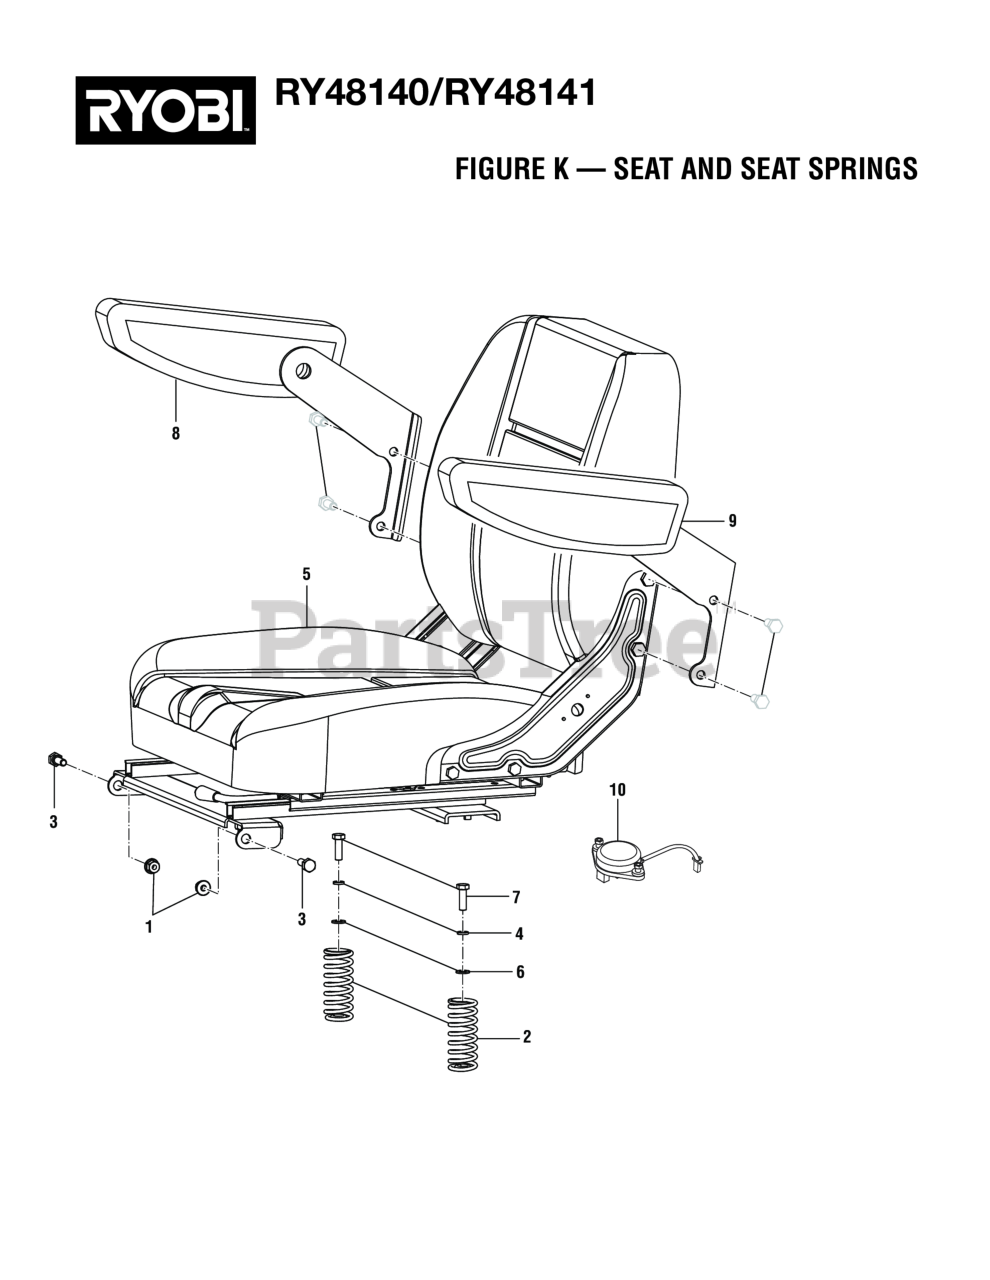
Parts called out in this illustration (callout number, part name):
1	Flange Nut (M8) (For Drive Motor Controller V)
2	Seat Spring, ZTR
3	Shoulder Bolt (M8 x 20 mm)
4	Lock Washer (OD9.8 x ID8.5 x 5t)
5	Seat, ZTR
6	Washer (OD16 x ID8.4 x 1.6t)
7	Bolt (M8 x 25 mm, Hex Hd.)
8	Long Armrest, Right
9	Long Armrest, Left
10	Seat Switch
